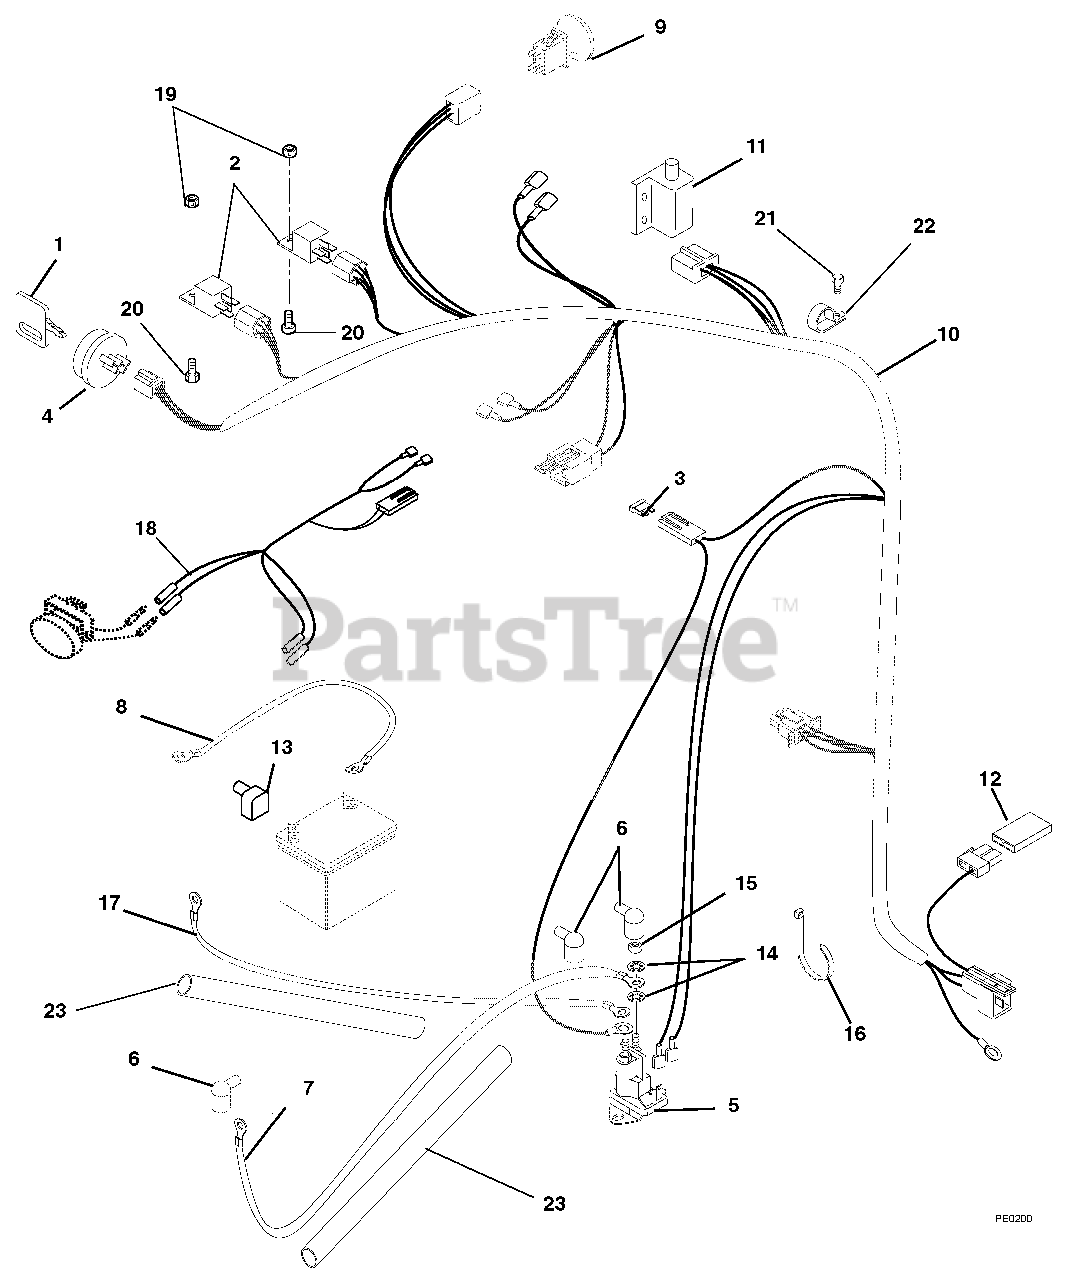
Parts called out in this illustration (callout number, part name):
1	KEY -W/CAP
2	RELAY
3	FUSE-25 AMP ATC TYPE
4	KEY SWITCH
5	SOLENOID, HP RTV
6	BATTERY, 12 VOLT SEALED AGM
7	BOOT, EYELET TERMINAL
8	STARTER CABLE
9	GROUND CABLE
10	SWITCH, CLUTCH
11	HARNESS, ZTXL/ZOOMXL
12	SWITCH- DOUBLE POLE N.O./N.O.
13	DIODE, CONNECTOR SHELL
14	INSULATOR
15	WSHR-LOCK INT .31 YWZC
16	NUT-JAM .31-24 YWZC
17	CABLE TIE LG 5-1/2
18	POSITIVE CABLE
19	HARNESS,MINI-Z HEADLIGHT
